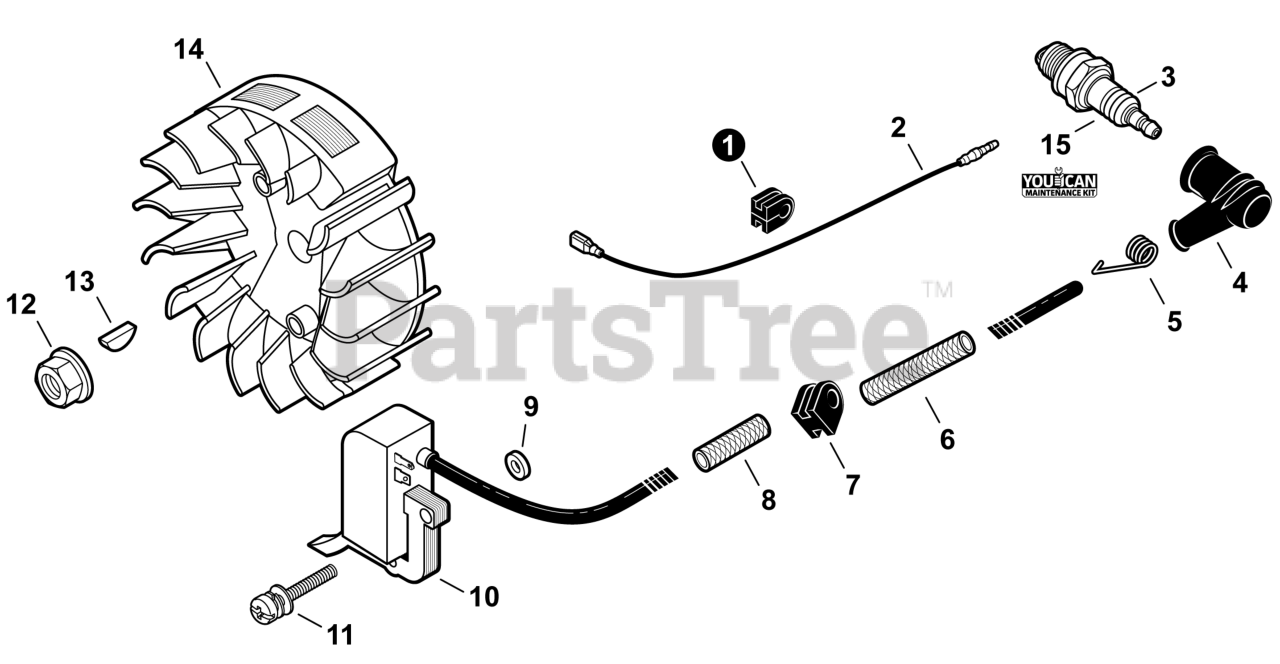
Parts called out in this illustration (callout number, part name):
2	LEAD - IGNITION
3	SPARK PLUG - BPMR8Y
4	CAP, SPARK PLUG
5	TERMINAL, SPARK PLUG
6	TUBE, INSULATOR 7x8.6x47
8	TUBE, INSULATOR 7x8.6x30
9	WASHER 5.2x12x3
10	COIL, IGNITION
11	SCREW 5x18
12	NUT, FLANGE M8
13	KEY, WOODRUFF
14	FLYWHEEL
15	TUNE-UP KIT - YOUCAN™
